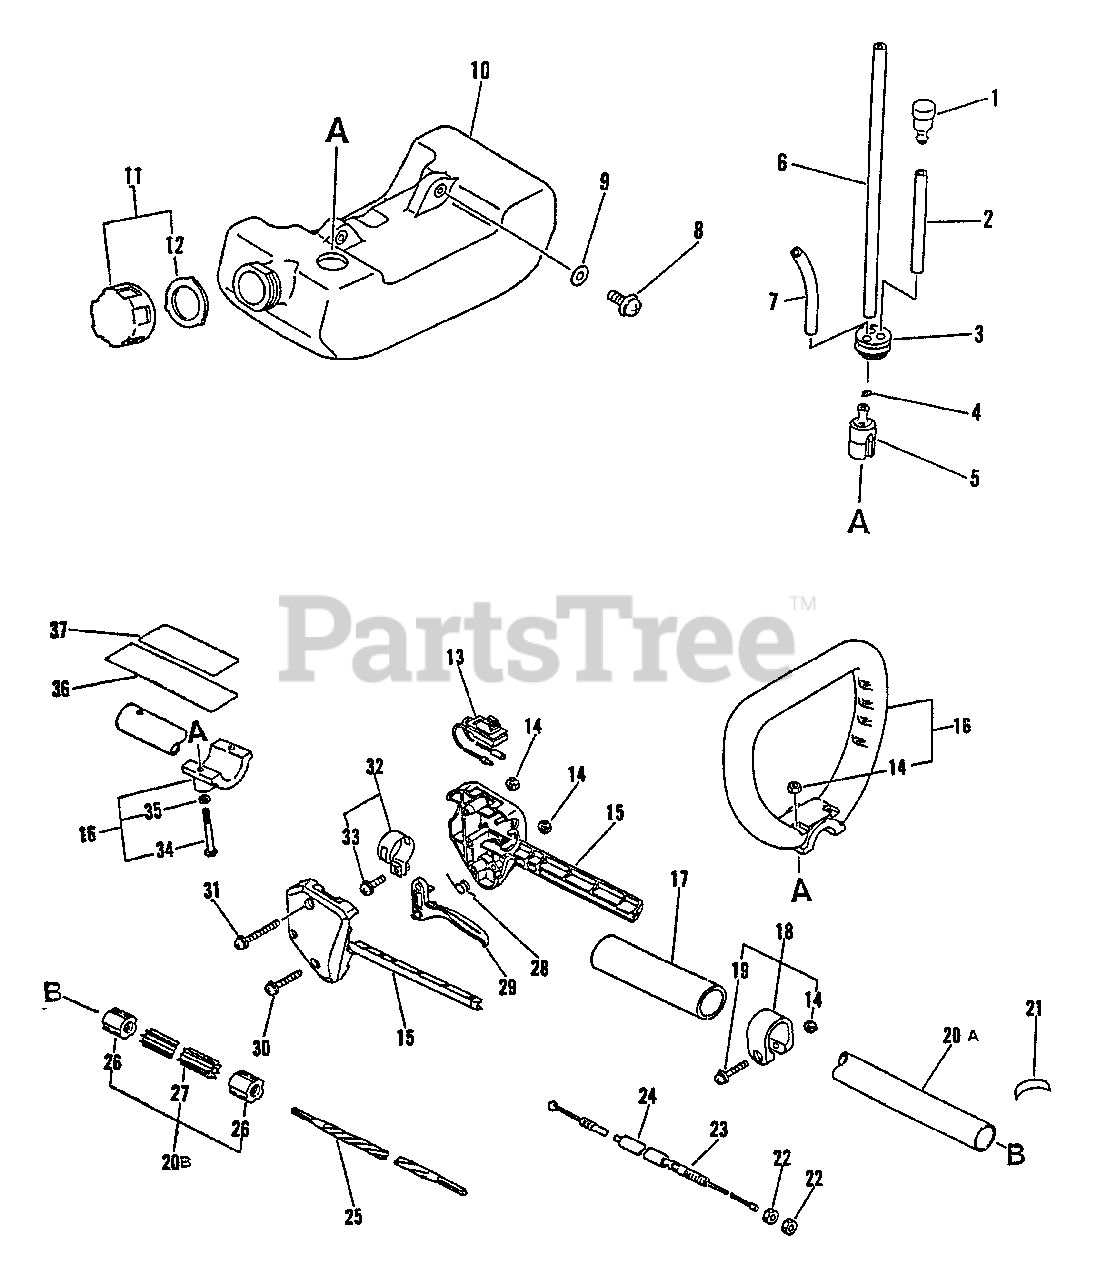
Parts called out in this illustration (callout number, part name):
1	Vent Asy
2	Pipe 3X5X70
3	Grommet, Fuel
5	Strainer, Fuel
6	Pipe, Fuel
7	Pipe 3X5X90
8	Screw 5X16
9	Washer 5
10	Tank, Fuel
11	Cap Asy, Fuel
12	Gasket, Fuel Tank Cap
13	Switch, Igniton
15	Bracket Set, Throttle
16	Handle Asy, Loop
17	Grip, Front Handle
18	Band 25
19	Screw 5X16
20	Housing Asy, Driveshaft
21	Label, Caution
22	Nut 6(3)
23	Wire, Throttle
25	Shaft, Flexible
26	Fixture, Liner
27	Liner, Flexible
28	Spring, Throttle Return
29	Contorl, Throttle
30	Screw 5X25
31	Screw 5X35
32	Band
33	Screw 5X14
34	Screw 5X140
35	Washer 5
36	Label, Caution
37	Label, Caution
